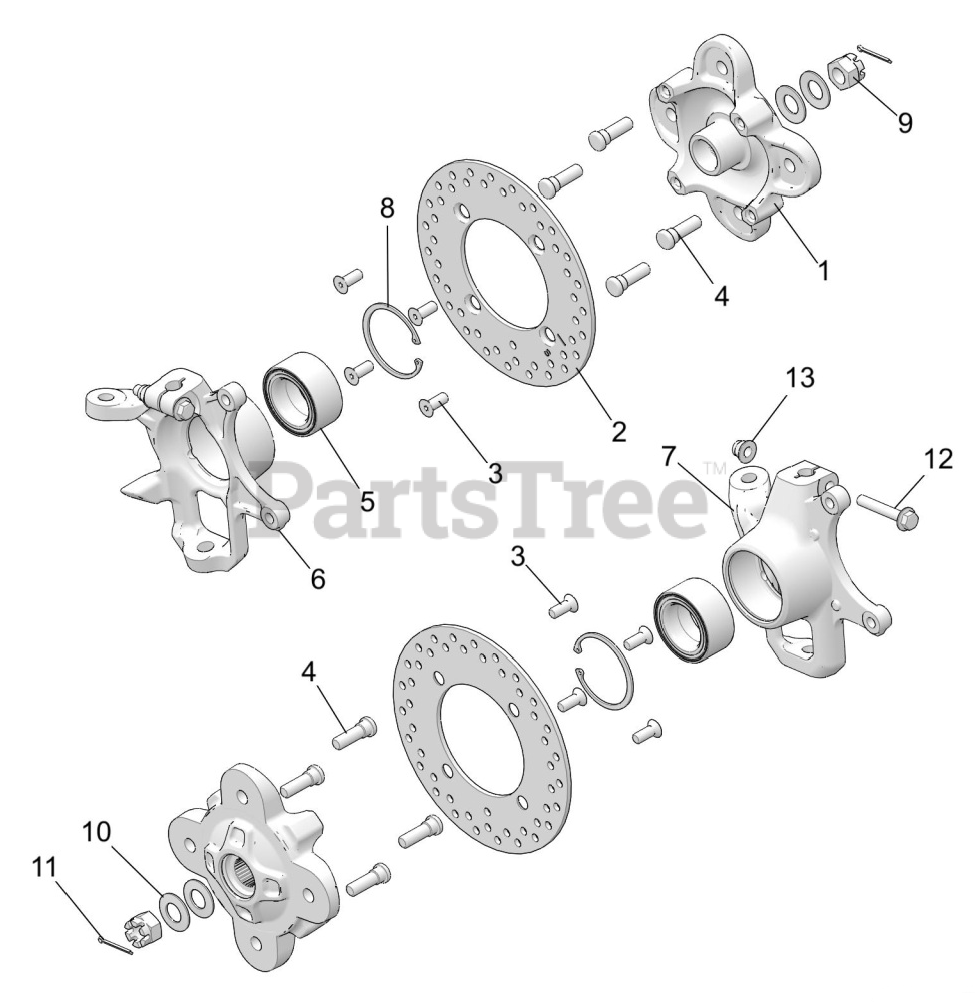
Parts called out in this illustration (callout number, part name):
1	HUB-WHEEL-FRONT MACH- BLK
2	ROTOR- BRAKE
3	SCR-M10X1.5X20 8.8 TXCS FL ZOD
4	STUD-WHEEL-M12-1.5
5	BEARING-BALL-SEALED-44X72X33.1
6	KNUCKLE-FRONT-LH
7	KNUCKLE-FRONT-RH
8	RING- RETAINING- INTERNAL
9	NUT-M18X1.5-CASTLE-ZINC/YELLOW
10	WASHER- CONE
11	PIN- COTTER
12	SCR-HXFL-M10X1.25X60 10.9 ZOD
13	NUT-M10X1.25-FLG-NYLOC-OLIVE D
